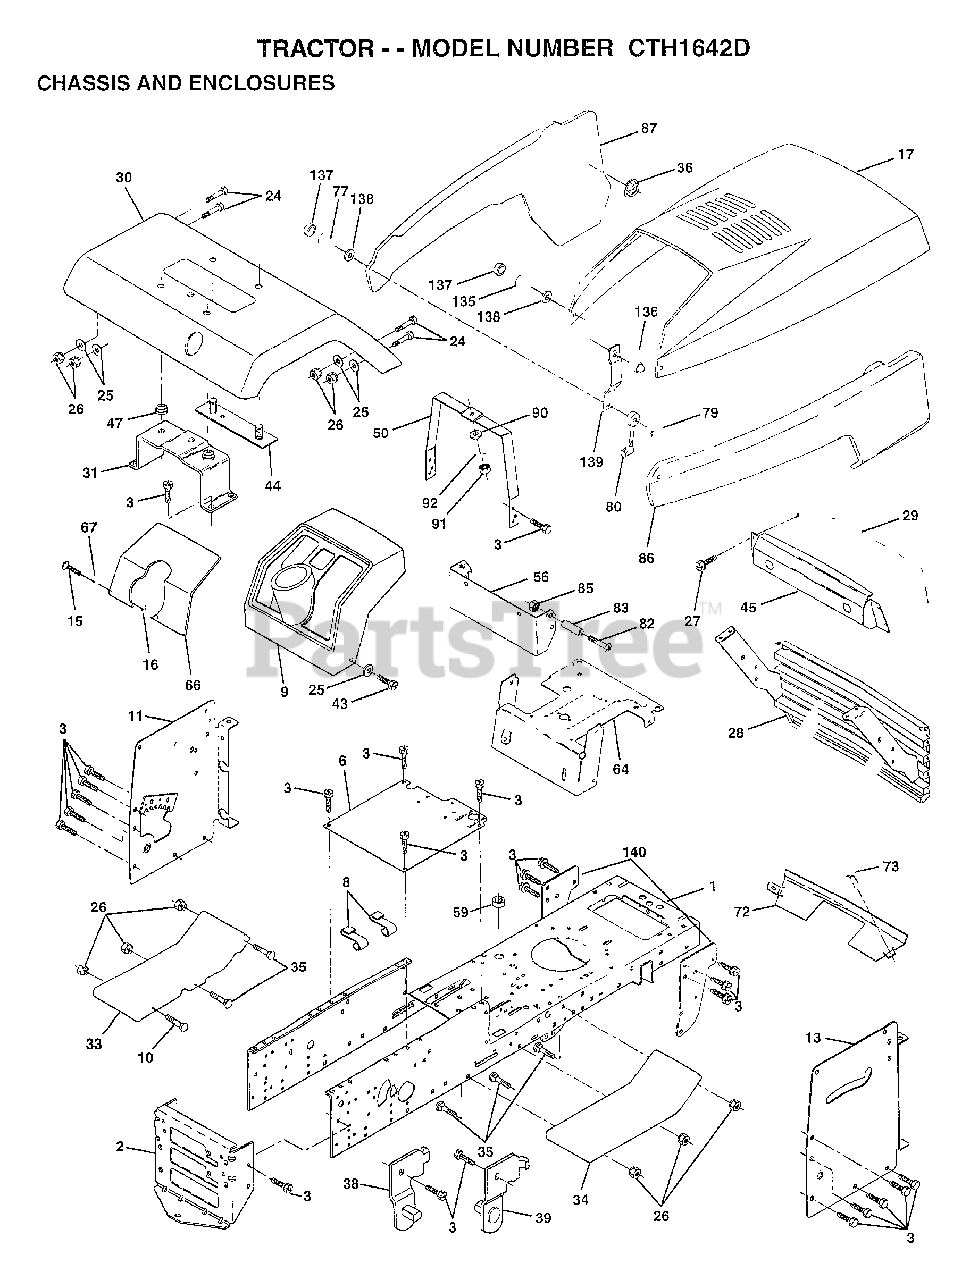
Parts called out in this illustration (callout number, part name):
1	CHASSIS ASM
3	SCREW
6	SADDLE
8	"CLIP,INSULATOR"
9	DASHBOARD BLACK
11	PANEL.DASH.LH.PNT
13	PANEL.DASH.RH.
15	SCREW
17	HOOD PNT YARDPRO
24	BOLT
25	WASHER
26	NUT
28	GRILLE ASM PNT
29	LENS.BAR.CLEAR
30	FENDER PNT
31	BRKT.ASM.FENDER
33	FOOTREST.LH.LT/GT
34	FOOTREST.RH.LT/GT
35	BOLT
36	PAL NUT LT
38	BRACKET ASM LH
39	BRACKET ASM RH
43	SCREW GTV
44	STRAP ASM FENDER
45	BEZEL.ASM.
47	NUT-PUSH YT
50	DASH.SUPT.YP/HUSQ
56	EXT DASH LTYT
64	DASH.LOWER.LT
66	"PLATE-DASH,SLKSCR"
67	WASHER
72	STRAP.PNT.GRILLE
73	SCREW CRT
77	SCREW
79	WELDNUT
80	HOOD LATCH T
82	SCREW
83	SPACER LT
86	PANEL PNT RH SIDE
87	PANEL PNT LH SIDE
90	WASHER PM
92	LOCKWASHER
135	SCREW.10-24X3/8.
136	ACORN NUT RB
137	SNAP CAP LT
138	WASHER LT
139	BKT.SPT.HOOD/PANL
140	BRKT SUSPENSION
